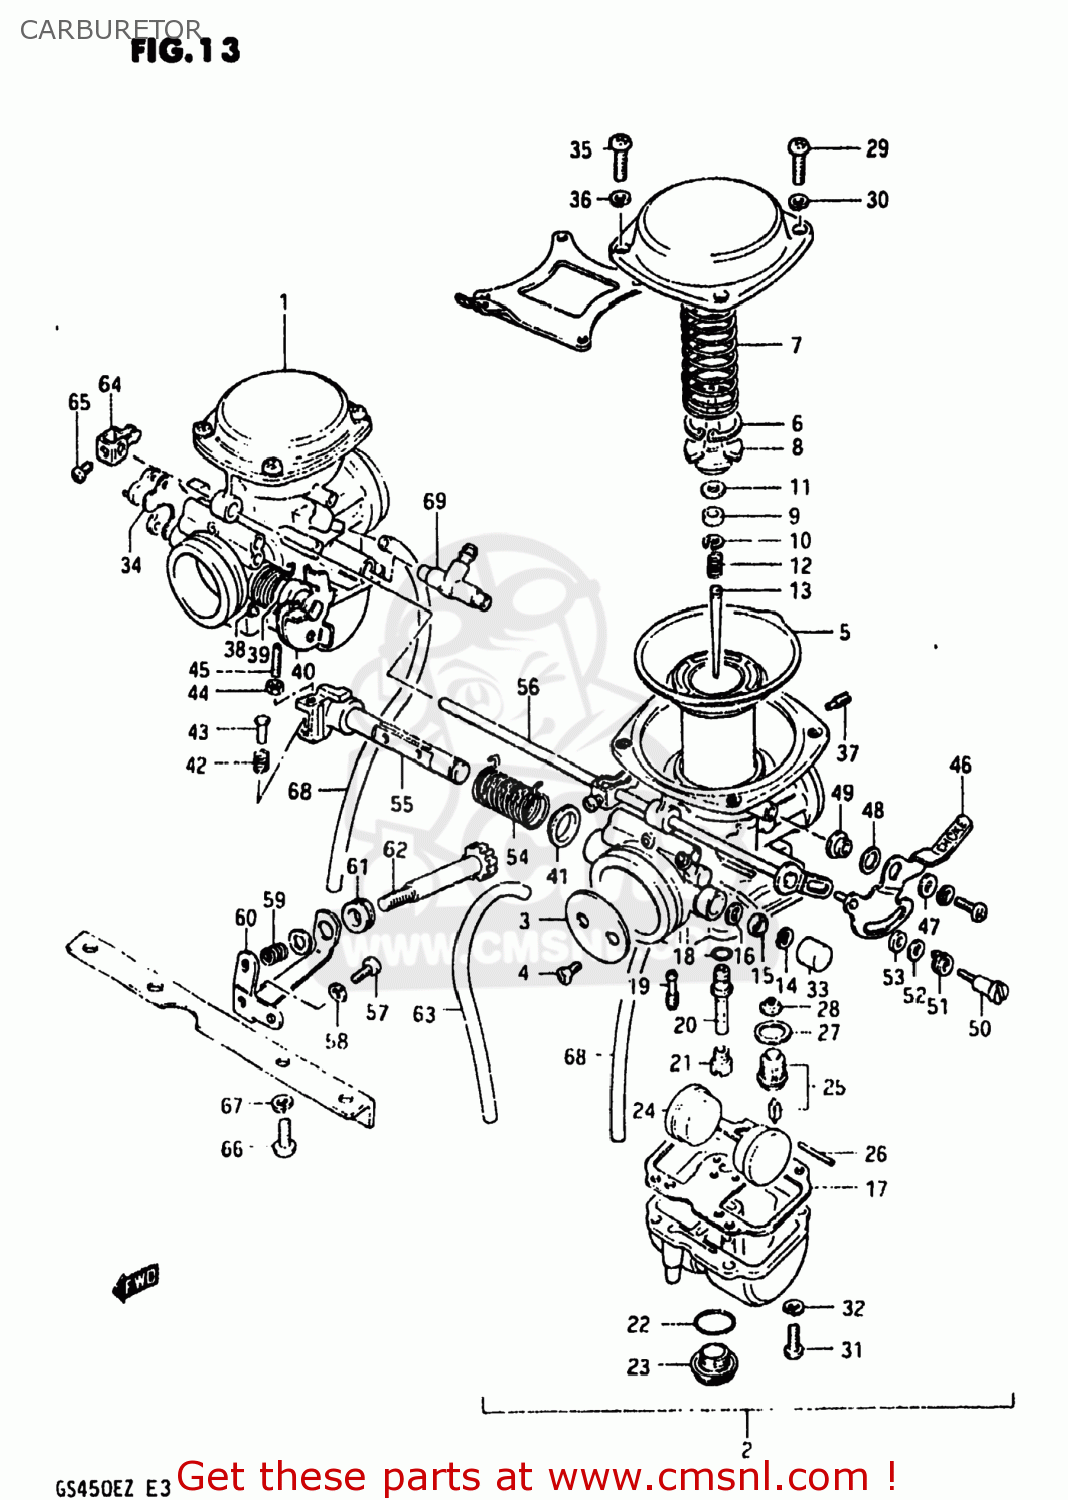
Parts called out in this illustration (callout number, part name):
1	CARBURETOR ASSEMBLY
2	CARBURETOR ASSEMBLY
3	VALVE,THROTTLE
4	SCREW
5	DIAPHRAGM
6	E RING
7	SPRING,DIAPHRAGM
8	HOLDER,GUIDE
9	RING
10	CLIP
11	WASHER
12	SPRING
13	NEEDLE JET
14	E RING
15	GASKET,THROTTLE SHAFT (NAS)
16	SEAL
17	GASKET,FLOAT CHAMBER (NAS)
18	O-RING
19	JET,PILOT
20	JET,NEEDLE
21	JET,MAIN(115)
22	O-RING
23	SCREW,GUIDE
24	FLOAT
25	VALVE ASSY,NEEDLE
26	PIN,FLOAT
27	GASKET,MAIN JET HOLDER (NAS)
28	FILTER
29	SCREW
30	LOCK WASHER
31	SCREW
32	LOCK WASHER
33	CAP
34	GASKET
35	SCREW
36	LOCK WASHER
37	JET,AIR(1.6)
38	SPRING
39	RING
40	SHAFT ASSEMBLY
41	RING
42	SPRING,THROTTLE SCREW
43	PIN,THROTTLE LEVER
44	NUT
45	SCREW
46	LEVER,STARTER
47	WASHER,STARTER LEVER (4.1X12X0.8)
48	WASHER,STARTER LEVER
49	RING,STARTER LEVER
50	SCREW
51	SPRING,STARTER LEVER S
52	WASHER
53	WASHER
54	SPRING
55	SHAFT ASSEMBLY
56	SHAFT,STARTER
57	SCREW
58	LOCK WASHER
59	SPRING
60	BRACKET,THROTTLE ADJUST
61	BUSHING,THROTTLE ADJUSTER
62	SCREW
63	HOSE 4.5X8X390
64	ARM, STARTER
65	SCREW
66	SCREW 6X12
67	LOCK WASHER
68	HOSE
69	NIPPLE
